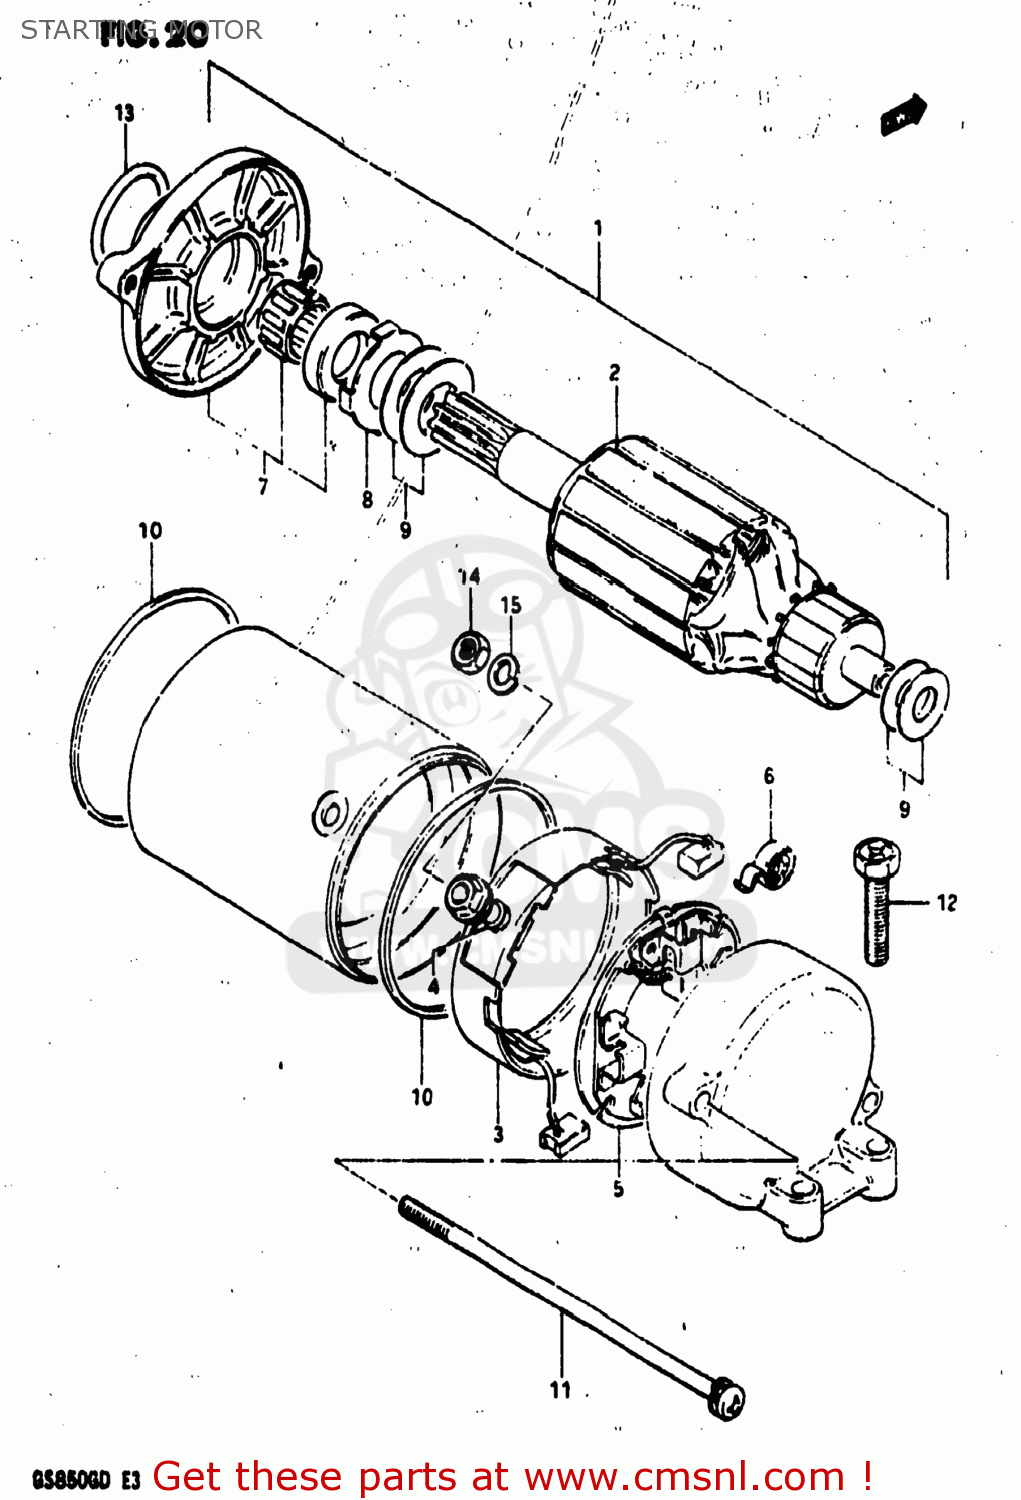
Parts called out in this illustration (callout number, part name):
1	MOTOR ASSEMBLY,STARTING
2	ARMATURE
3	BRUSH TERMINAL SET (+)
4	O RING
5	HOLDER,BRUSH
6	SPRING,BRUSH
7	HOUSING SET,STARTING MOTOR
8	SHIM SET
9	SHIM SET
10	SEAL,RING
11	BOLT,STARTING MOTOR HOUSING
12	SCREW (6X25)
13	O RING(D:2,ID:24.5)
14	NUT 6MM
15	LOCK WASHER
